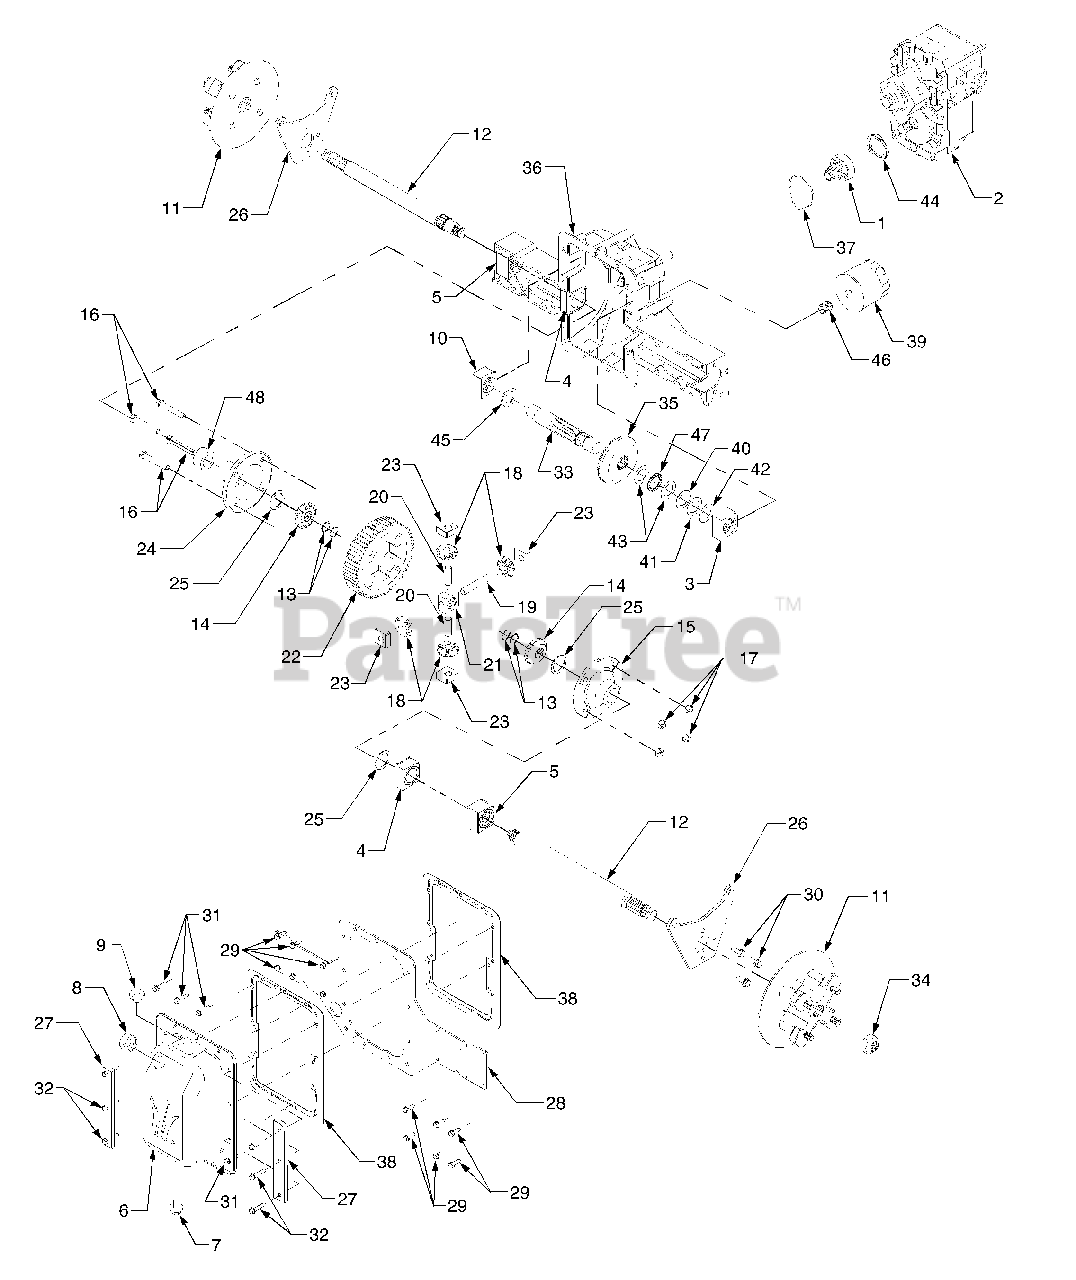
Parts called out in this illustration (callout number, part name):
1	Gear Assembly, Pinion 13T
2	Hydrostatic Transmission Assy. Kit
3	Bearing Block Assembly, Needle
4	Bearing Block Assembly
5	Bearing Block Assembly
6	Cover Assembly, Rear
7	Plug, Drain, M14 x 1.5 x .827
8	Grommet, Rubber
10	Bearing Block Assembly
11	Hub Assembly, Wheel
12	Axle Shaft, 15.08 Long
13	Retaining Ring
14	Gear, Spur, 14T
15	Housing, Diff. Cover
16	Hex Cap Screw, 3/8-24 x 2.25 GR5
17	Nut, Hex Lock, 3/8-24
18	Gear, Differential 10T
19	Shaft, Cross, .5 x 3.485
20	Shaft, Cross, Special
21	Differential Pinion Block
22	Gear, Spur 60T
23	Block, Thrust Miter
24	Housing, Differential Cover
25	Washer, Flat, 1.187 x 1.56 x .062
26	Bracket, Brake Mounting
27	Block, Transmission Cover
28	Plate, Transmission
29	Screw, Hex Wash. Hd. Tapp 1/4-20 x .75
30	Screw, Hex Wash. Hd. Tapp 5/16-18 x .875
31	Screw, Hex Wash. Hd. Tapp 1/4-20 x 1.0
32	Screw, Hex Wash. Hd. Tapp 1/4-20 x 1.25
33	Shaft, Output 9T
34	Nut, Lock, 7/8-14
35	Gear, Bevel 54T
36	Differential Housing Service Kit
37	O-Ring, 2.75 x .103
38	Gasket
39	Filter, Oil
40	Washer, Flat Shim, 1.0 x 1.56 x .010
41	Washer, Flat Shim, 1.0 x 1.56 x .020
42	Washer, Flat Shim, 1.0 x 1.56 x .015
43	Washer, Thrust, 1.007 x 1.542 x .03
44	Washer, Spring
45	Washer, Flat, 1.01 x 1.86 x .060
46	Fitting, Filter Nipple
47	Bearing, Needle Thrust
48	Spacer, Axle, 1.188 x 1.665 x .67
